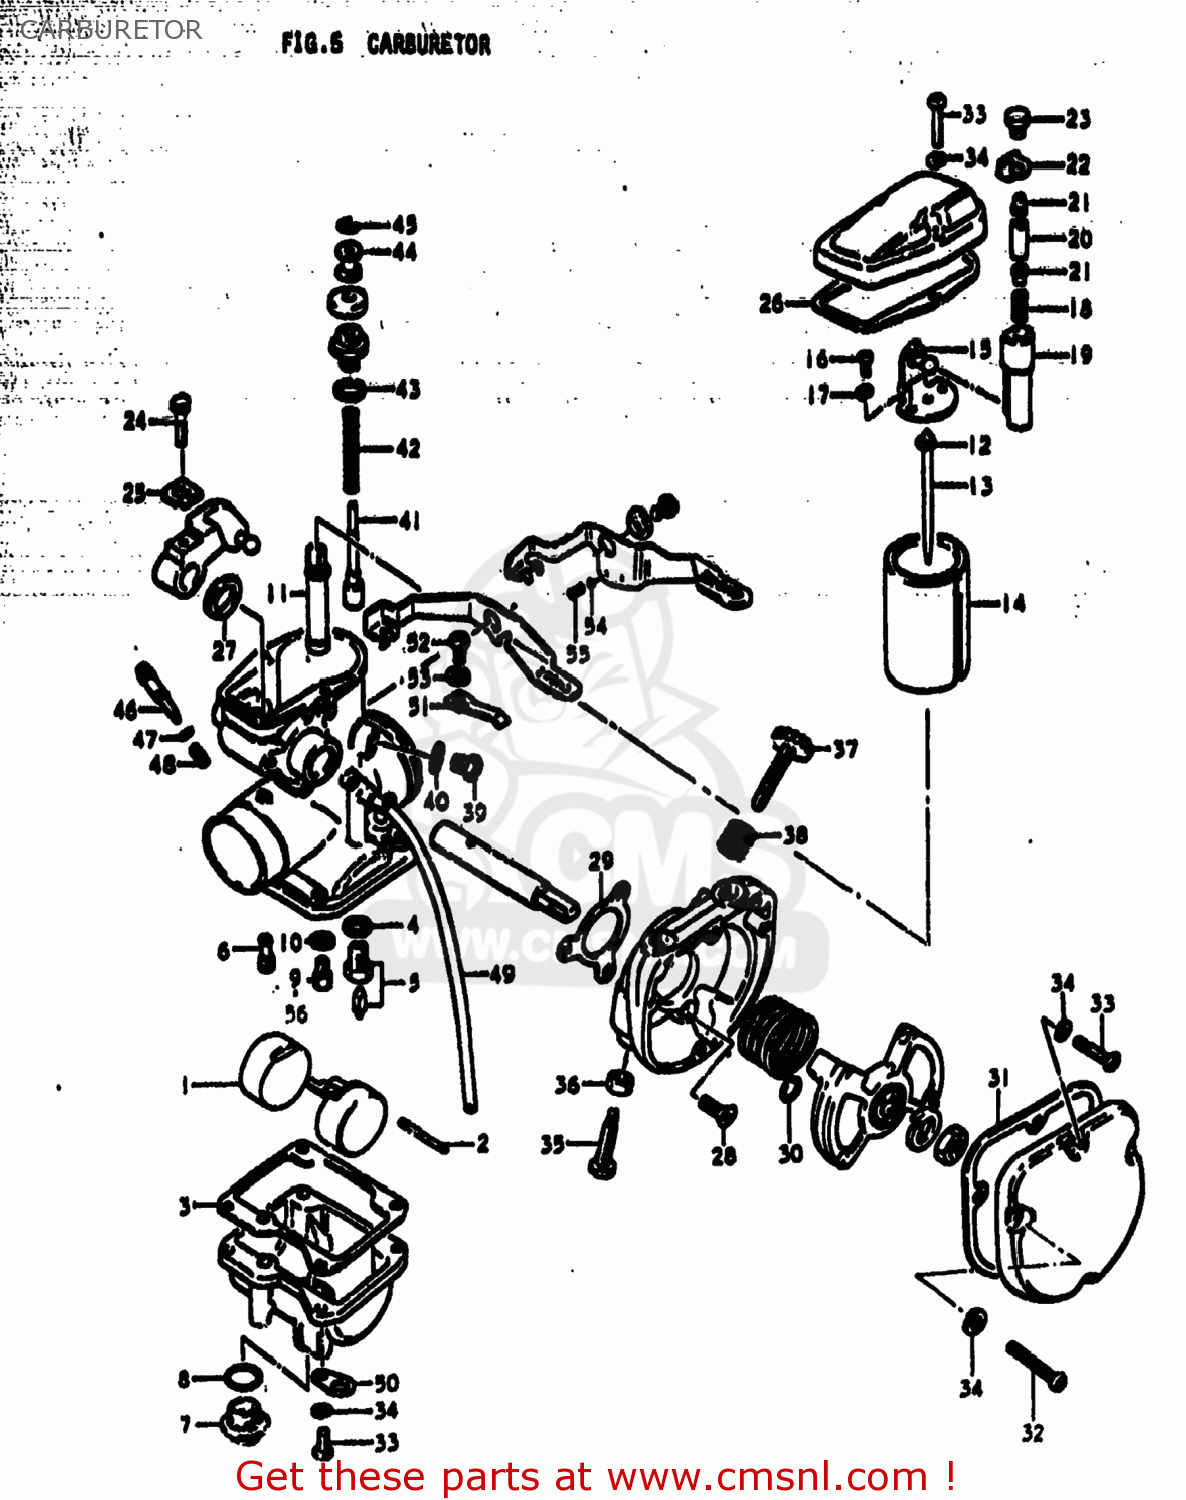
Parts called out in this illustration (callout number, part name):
1	FLOAT
2	PIN,FLOAT
3	GASKET,FLOAT CHAMBER (NAS)
4	GASKET,VALVE SEAT (NAS)
5	VALVE ASSEMBLY,NEEDLE
6	JET,PILOT(22.5)
7	PLUG,DRAIN
8	O RING
9	JET,MAIN(125)
10	WASHER
11	JET,NEEDLE
12	VALVE,THROTTLE
13	NEEDLE JET
14	CLIP
15	PLATE,THROTTLE VALVE
16	SCREW
17	LOCK WASHER
18	RING
19	WASHER,JET NEEDLE
20	BRACKET,CARBURETOR
21	SPRING
22	SPRING
23	LEVER ASSEMBLY
24	SPRING
25	PIN,CARBURETOR
26	SCREW
27	PLATE,CARBURETOR
28	BOLT
29	RING
30	GASKET,MIXING CHAMBER (NAS)
31	RING
32	GASKET,CARBURETOR CASE
33	SCREW(5X12)
34	SPRING
35	GASKET,CARBURETOR COVER
36	SCREW
37	LOCK WASHER
38	SCREW 4X25
39	LOCK WASHER
40	SCREW
41	LOCK WASHER
42	SCREW
43	NUT 6MM
44	SCREW,THROTTLE STOP
45	SPRING,THROTTLE SCREW
46	GASKET,THRO VALVE INSPECTION (NAS)
47	BOLT
48	BALL,STARTER SHAFT
49	SPRING
50	SCREW,PILOT AIR ADJUSTING
51	O RING
52	SPRING
53	VALVE,STARTER
54	SPRING
55	O-RING
56	RING
57	CLIP,CARBURETOR STARTER
58	HOSE
59	PLATE
